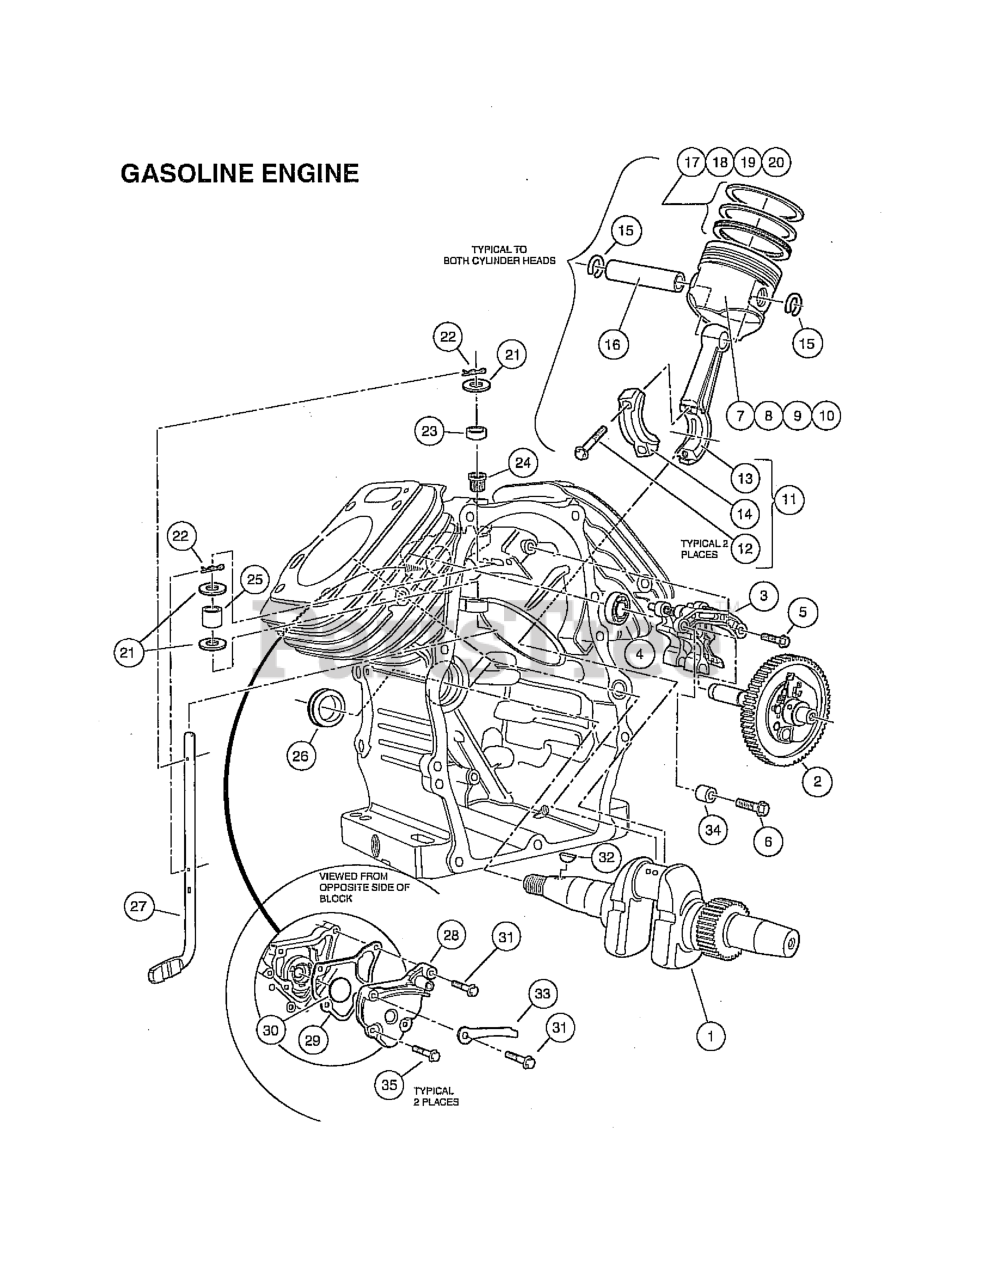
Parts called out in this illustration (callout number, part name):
1	CRANKSHAFT
2	CAMSHAFT ASSY.
3	LIFTER ASSY., VALVE
4	BEARING, RADIAL BALL, 6003
5	BOLT, FLANGE, M5 X 1 X 16
6	BOLT, FLANGE, M6 X 1 X 25
7	PISTON, STD
8	PISTON, OS 0.25
9	PISTON, OS 0.50
10	PISTON, 0.75
11	ROD ASSY., CONNECTING
12	BOLT, CONNECTING ROD, 6 X 37
15	2LIP, PISTON PIN, 18MM
16	PIN, PISTON
17	RING SET, PISTON, STD
18	RING SET, PISTON, OS 0.25
19	RING SET, PISTON, OS 0.50
20	RING SET, PISTON, OS 0.75
21	WASHER, PLAIN, M8
22	PIN, LOCK, 8MM
23	BEARING, NEEDLE, 8 X 12.7 X 11
24	OIL SEAL, 8 X 14 X 5
25	BEARING, NEEDLE, 8 X 12 X 10
26	OIL SEAL, 38 X 58 X 9
27	SHAFT, GOVERNOR ARM
28	COVER, BREATHER
29	GASKET, BREATHER COVER
30	VALVE, BREATHER
31	BOLT, FLANGE, M6 X 1 X 32
32	KEY, SPECIAL WOODRUFF, 25 X 18
33	CLAMP, WIRE
34	PIN A, DOWEL
35	BOLT, FLANGE, 6 X 16
